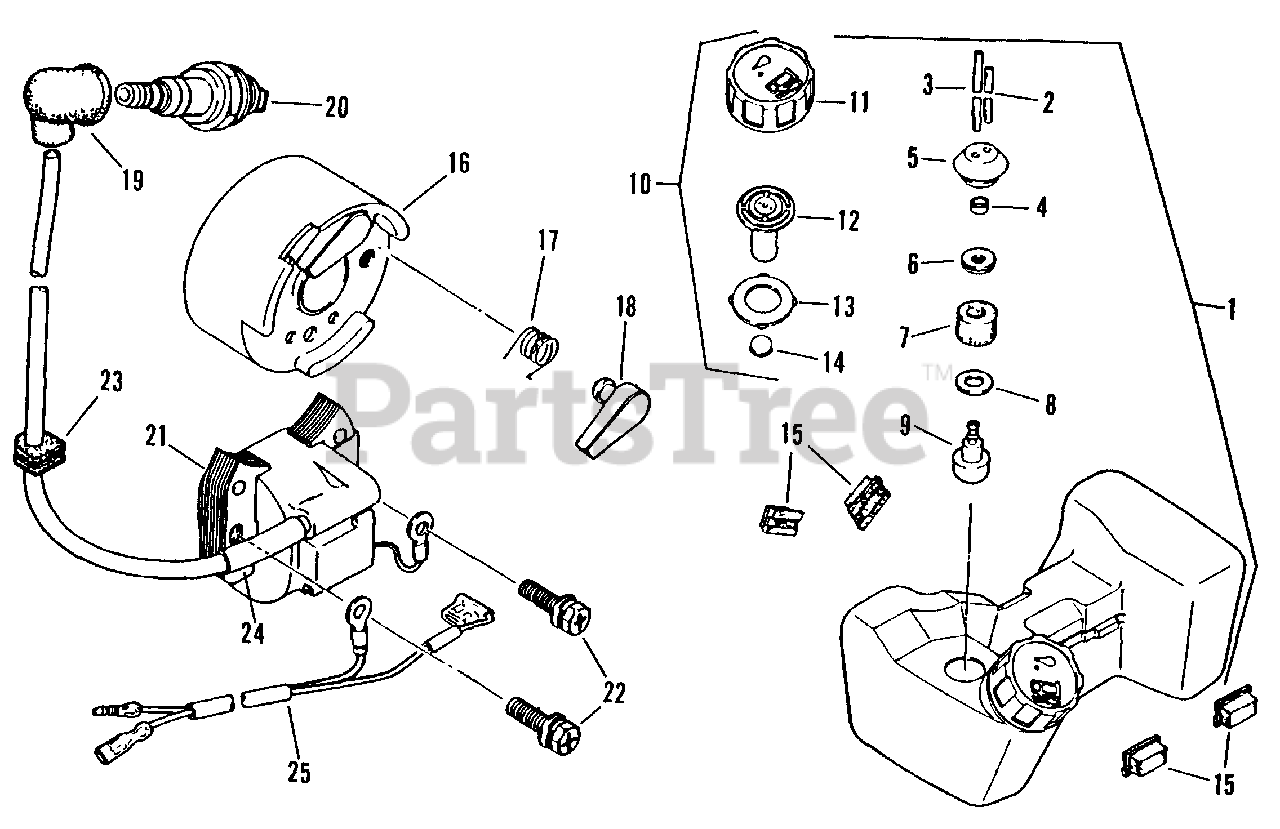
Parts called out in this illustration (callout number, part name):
1	ASSEMBLY, Fuel Tank
2	TUBE, Fuel
3	HOSE, Fuel
4	BUSHING
6	WASHER, Seal
7	FILTER, Fuel
8	SEAL, Dust
9	WEIGHT, Filter
10	ASSEMBLY, Tank Cap
11	CAP, Fuel Tank
12	VALVE, Breather
13	PACKING
16	ROTOR
17	SPRING, Return
18	RATCHET
19	CAP, Plug
21	COIL, Ignition
22	BOLT/WASHER
23	GROMMET
25	ASSEMBLY, Wire Lead
